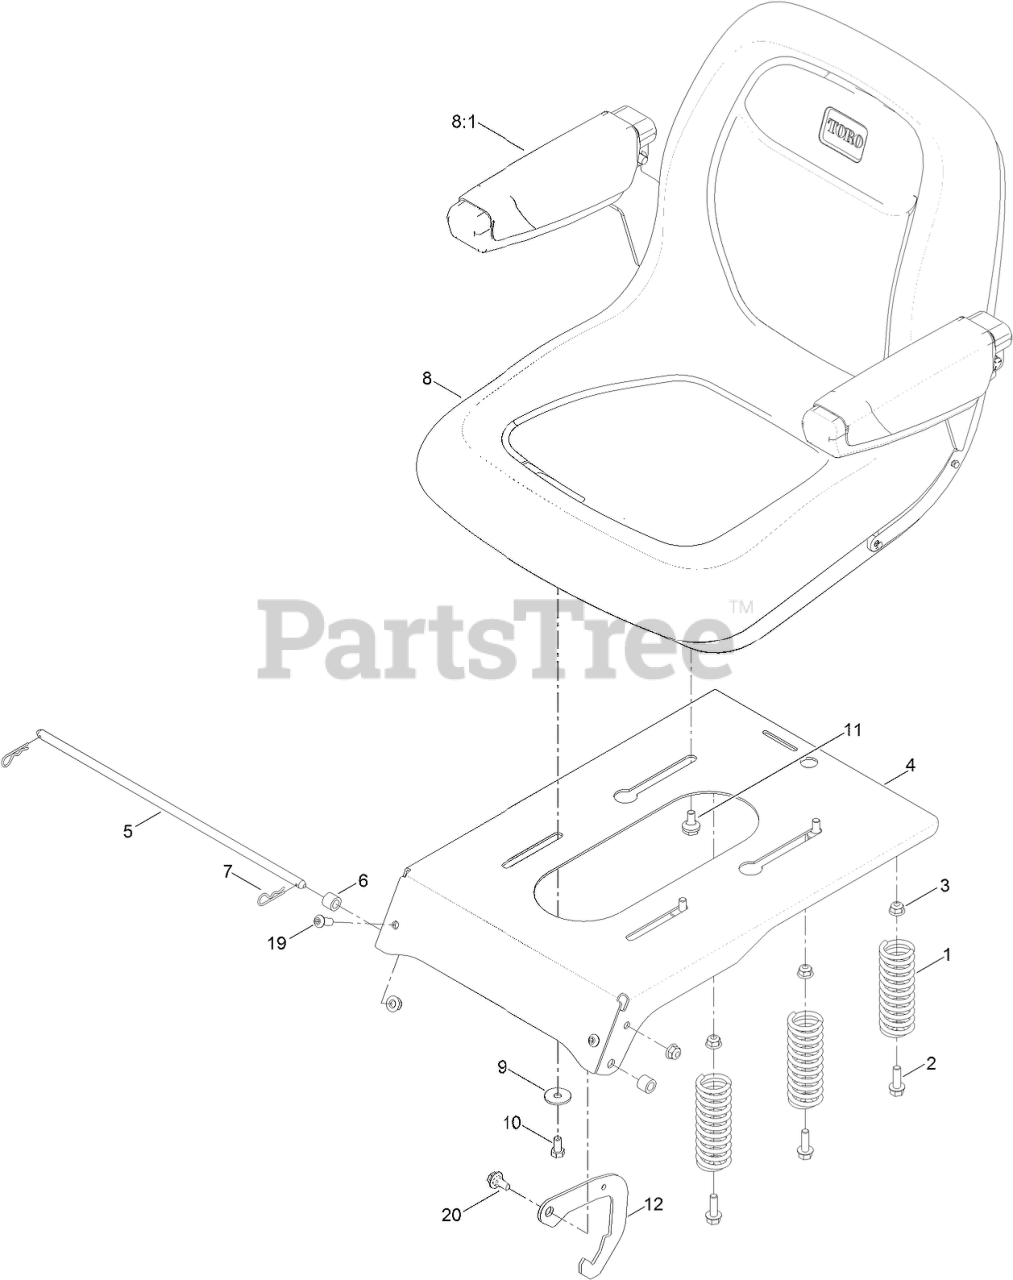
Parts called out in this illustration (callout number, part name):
1	SPRING-COMPRESSION
2	SCREW-HHF
3	NUT-HF, NI
4	PAN-SEAT
5	ROD-STOP
6	BUSHING-LEVER, LIFT
7	PIN-COTTER
8	SEAT-18 Inch
8:1	ARMREST KIT (MILSCO)
9	WASHER-PIVOT
10	SCREW-HH
11	BOLT-SHOULDER
12	LATCH-SEAT
19	SCREW-HSBH
20	SCREW-SHOULDER
